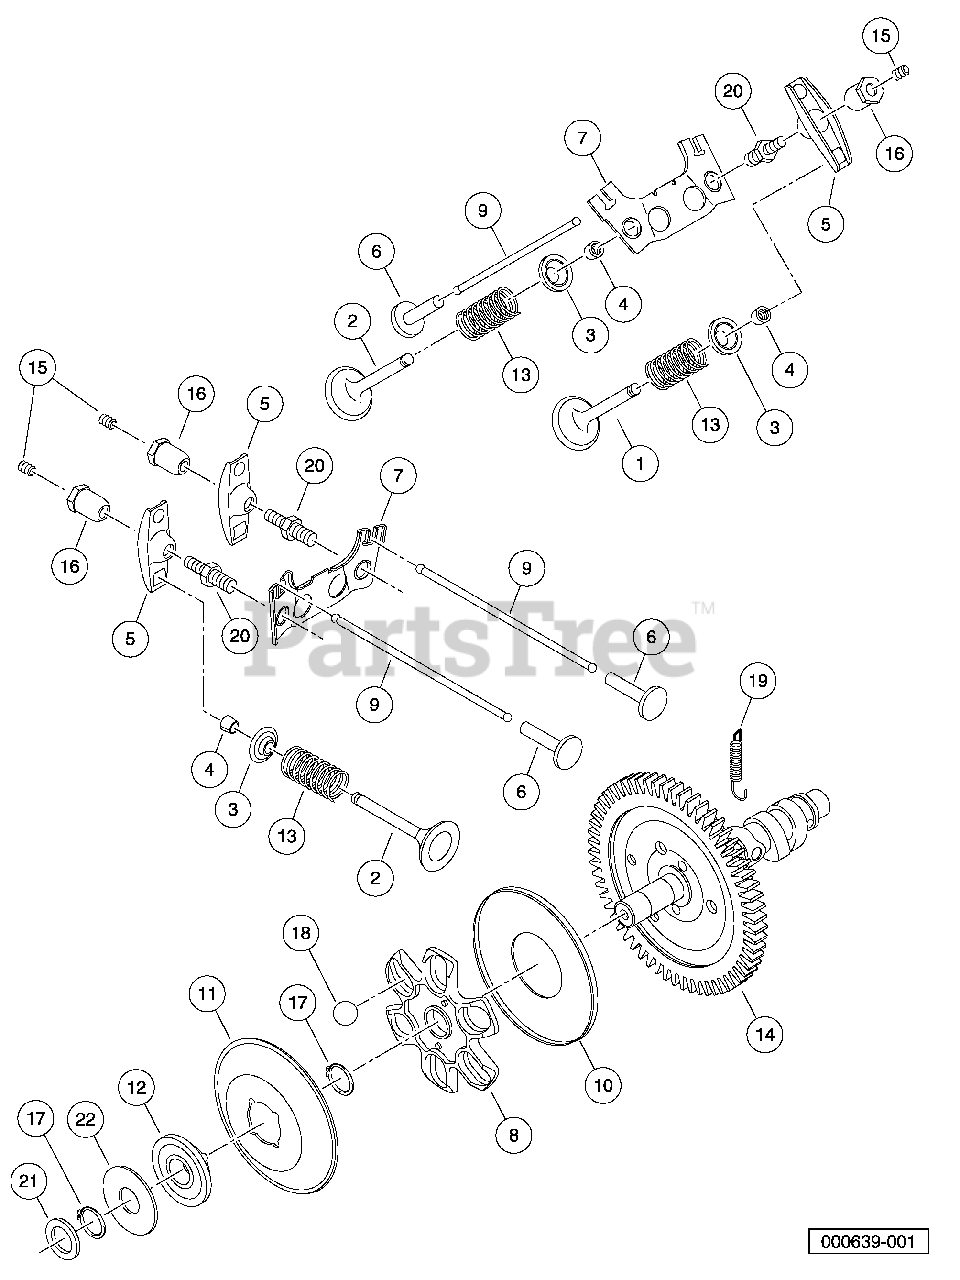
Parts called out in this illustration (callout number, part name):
1	Valve, Intake, Fh
2	Valve, Exhaust, Fh
3	Retainer, Valve Spring, Fh
4	Collet, Spring, Valve, Fh
5	Arm, Rocker
6	Tappet, Rod, Push, Fh
7	Guide, Arm, Rocker, Fh
8	Guide, Camshaft, Gov, Fh
9	Rod, Push, Fh
10	Plate, Camshaft, Gov, Fh
11	Plate, Ring, Gov, Fh
12	Sleeve, Plate, Gov, Fh
13	Spring, Valve, Fh
14	Kit, Camshaft, Comp, Fh
15	Screw, Rocker Arm, Fh
16	Nut, Arm, Rocker, Fh
17	Ring, Snap, Gov, Fh
18	Ball, Guide, Gov, Fh
19	Spring, Camshaft, Fh
20	Stud, Rocker Arm, Fh
21	Washer, Sleeve, Gov, Fh
22	Washer, Gov, Fh
